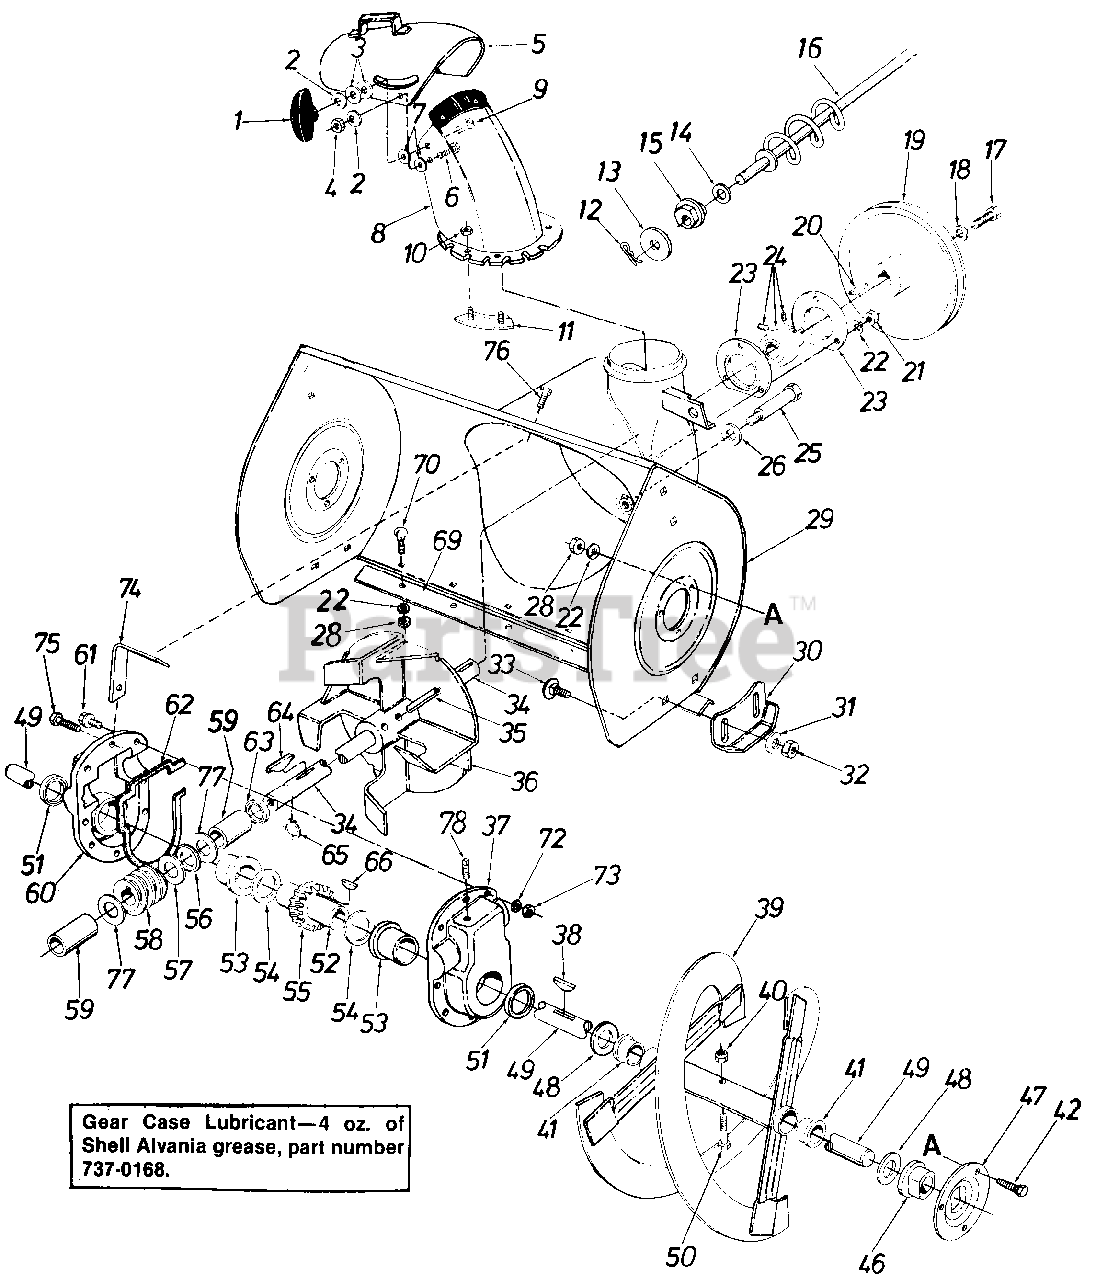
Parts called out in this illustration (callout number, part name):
1	Hand Knob Ass'y.
2	Bell-Wash. .345 I.D. x .88 O.D. x .060
3	Fl. Wash. .312 I.D. x 1.125 O.D. x .125
4	Hex Cent. L-Nut 5/16-18 Thd.
5	Top Chute Ass'y.
6	Carr. Bolt 5/16-18 x .62" Lg.
7	Fl-Wash. .53 I.D. x 1.25 O.D. x .100
8	Chute Ass'y.
9	Carr. Bolt 5/16-18 x 1.00" Lg.
10	Hex Cent. L-Nut 1/2-20 Thd.
11	Chute Flange Keeper Ass'y.
12	Cotter Pin
13	Fl-Wash. .390" I.D. x 1.50" O.D.
14	Fl-Wash. .385" I.D. x .62" O.D.
15	Hex Bushing
16	Chute Crank Ass'y.
17	Hex L-Scr. 5/16-18 x .88" Lg.
18	Bell-Wash. .345 I.D. x .88 O.D. x .060
19	V-Pulley .875 I.D. x 10.12 O.D.
20	#9 Hi-Pro Key 3/16 x 3/4" Dia.
21	Hex Nut 5/16-18 Thd.
22	L-Wash. 5/16" Scr.
23	Bearing Hsg. - Self Aligning Brg.
24	Self Aligning Brg. .875 I.D.
25	Stud 3/8-16 x 2.75" Lg.
26	Bell-Wash. .400 1.D. x .88 O.D. x .060
28	Hex Nut 5/16-18 Thd.
29	Blower Hsg. Ass'y.
30	Slide Shoe
31	Bell-Wash. .400 I.D. x .88 O.D. x .060
32	Hex Jam Nut 3/8-16 Thd.
33	Carr. Bolt 3/8-16 x .62" Lg.
34	Blower Axle
35	Spring Pin Spiral 5/16" Dia. x 1.75" Lg.
38	#91 Woodruff Key 1/4" x 3/4" Dia.
41	Plastic Bushing
42	Hex Sems Scr. 5/16-18 x .75" Lg.
46	Flange Brg. w/Flats 1.0" I.D.
47	Bearing Hsg.- Spiral Hsg.
48	Fl-Wash. 1.06 I.D. x 1.75" O.D. x .100
49	Spiral Axle - 26"
50	Hex Bolt 5/16-18 x 1.75" Lg.
51	Oil Seal 1.50" I.D.
52	Worm Gear Shaft
53	Flange Brg. 1.503 I.D.
54	Fl-Wash. 1.50 I.D. x 2.00 O.D. x .030
55	Double Threaded Worm Gear
56	Thrust Brg. .88 I.D. x 1.44 O.D. x .078
57	Fl-Wash. .88 I.D. x 1.40 O.D. x .150
58	Double Threaded Worm - L.H.
59	Sleeve Brg. .875 I.D.
60	Complete Gear Hsg. Half - R.H.
61	Hex Scr. 5/16-18 x 1.00" Lg.
62	Gasket
63	Oil Seal .875" I.D.
64	#9 Hi-Pro Key 3/16 x 3/4" Dia.
65	Snap Ring for .875" Dia. Shaft
66	#91 Woodruff Key 1/4 x 3/4" Dia.
72	Wave Wash. 5/16" Scr.
73	Hex Ins. L-Nut 5/16-18 Thd.
74	Gear Hsg. Support Brkt.
75	Hex Scr. 5/16-18 x 1.25" Lg.
76	Hex Wash. Hd. Self-Tap Scr. 5/16-38 x .75" Lg.
77	Fl-Wash. .88 I.D. x 1.40 O.D. x .150
78	Filler Plug
